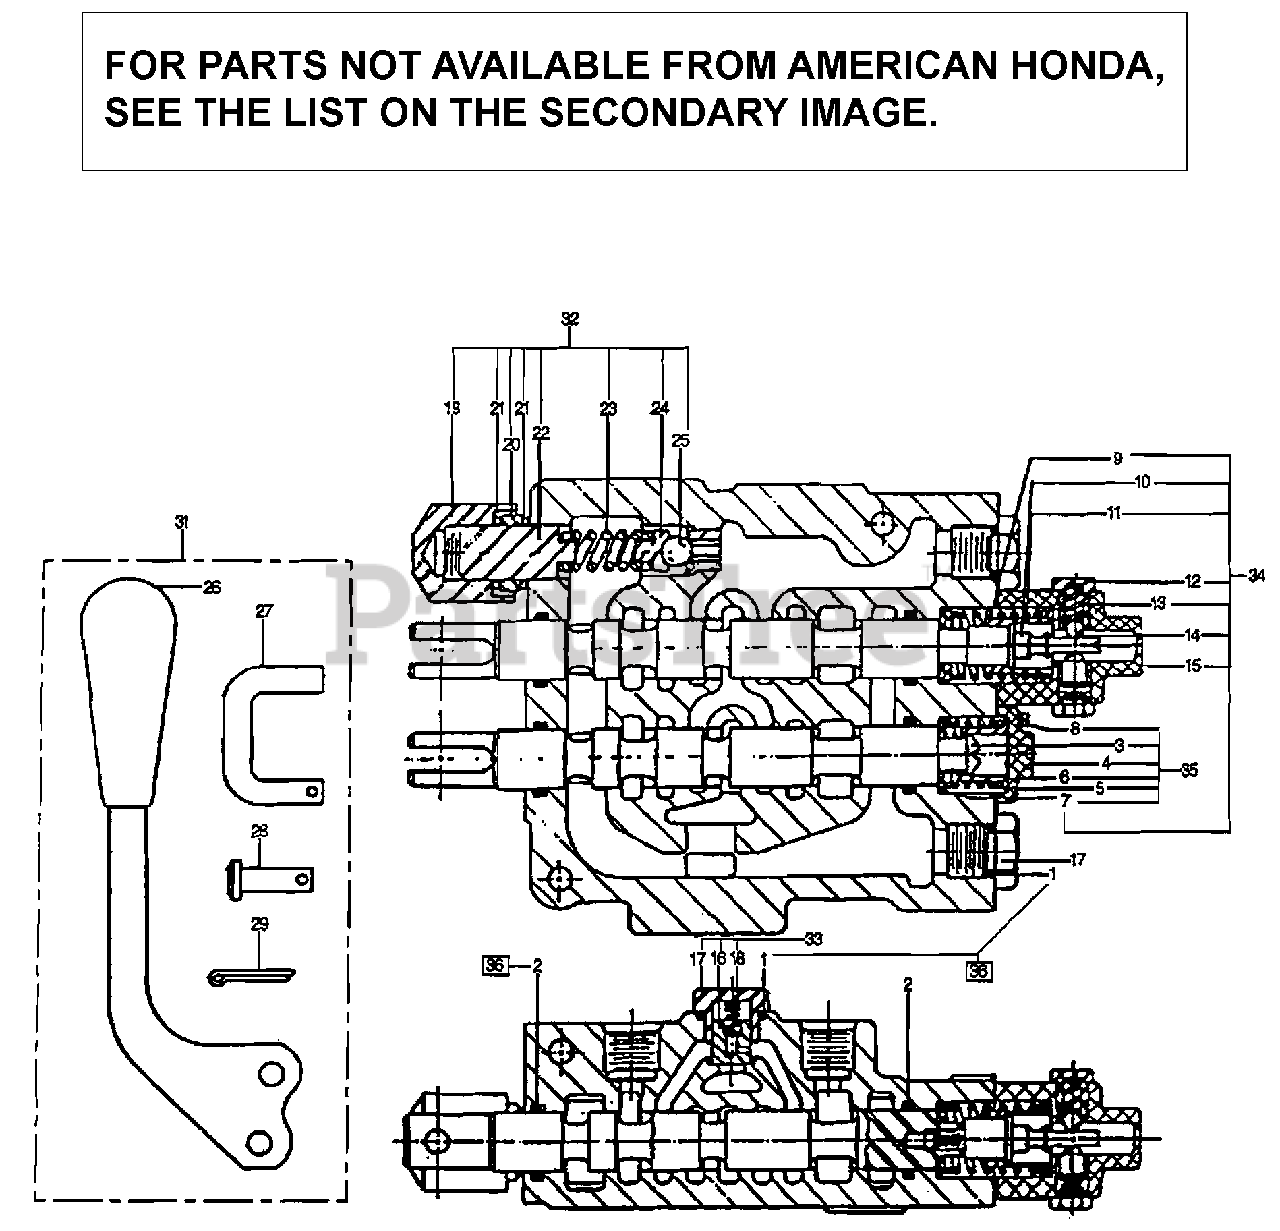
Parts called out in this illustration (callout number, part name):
31	HANDLE KIT
32	VALVE KIT, RELIEF
33	LOAD CHECK KIT
34	DETENT & FLOAT KIT
35	SPRING CENTERING KIT
36	SEAL KIT
